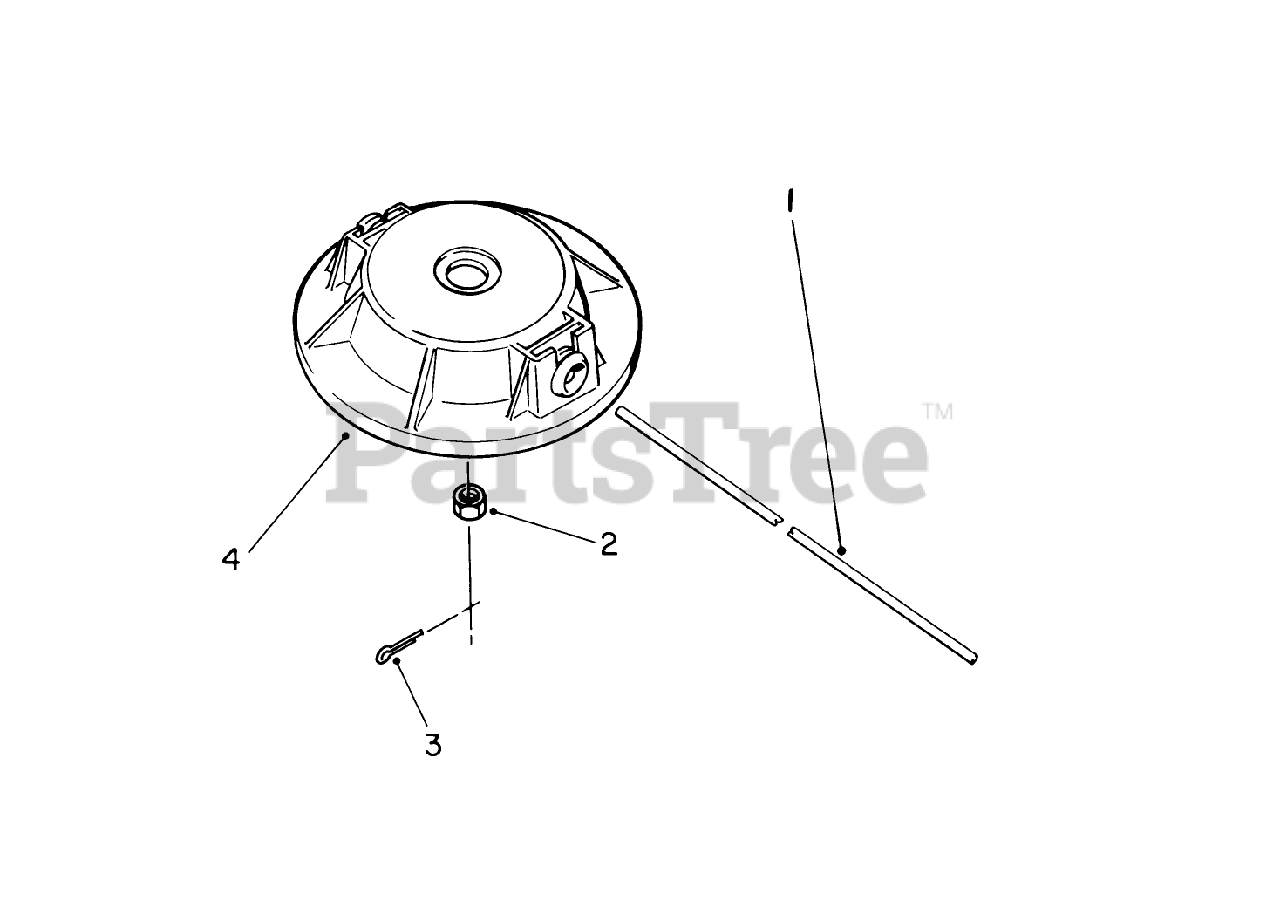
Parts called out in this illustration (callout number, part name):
1	LINE PACK (100)
2	SPACER
3	Head Assembly (Incl. Ref. #2)
4	WASHER
6	1/16 X 1 LG COTTER PIN
